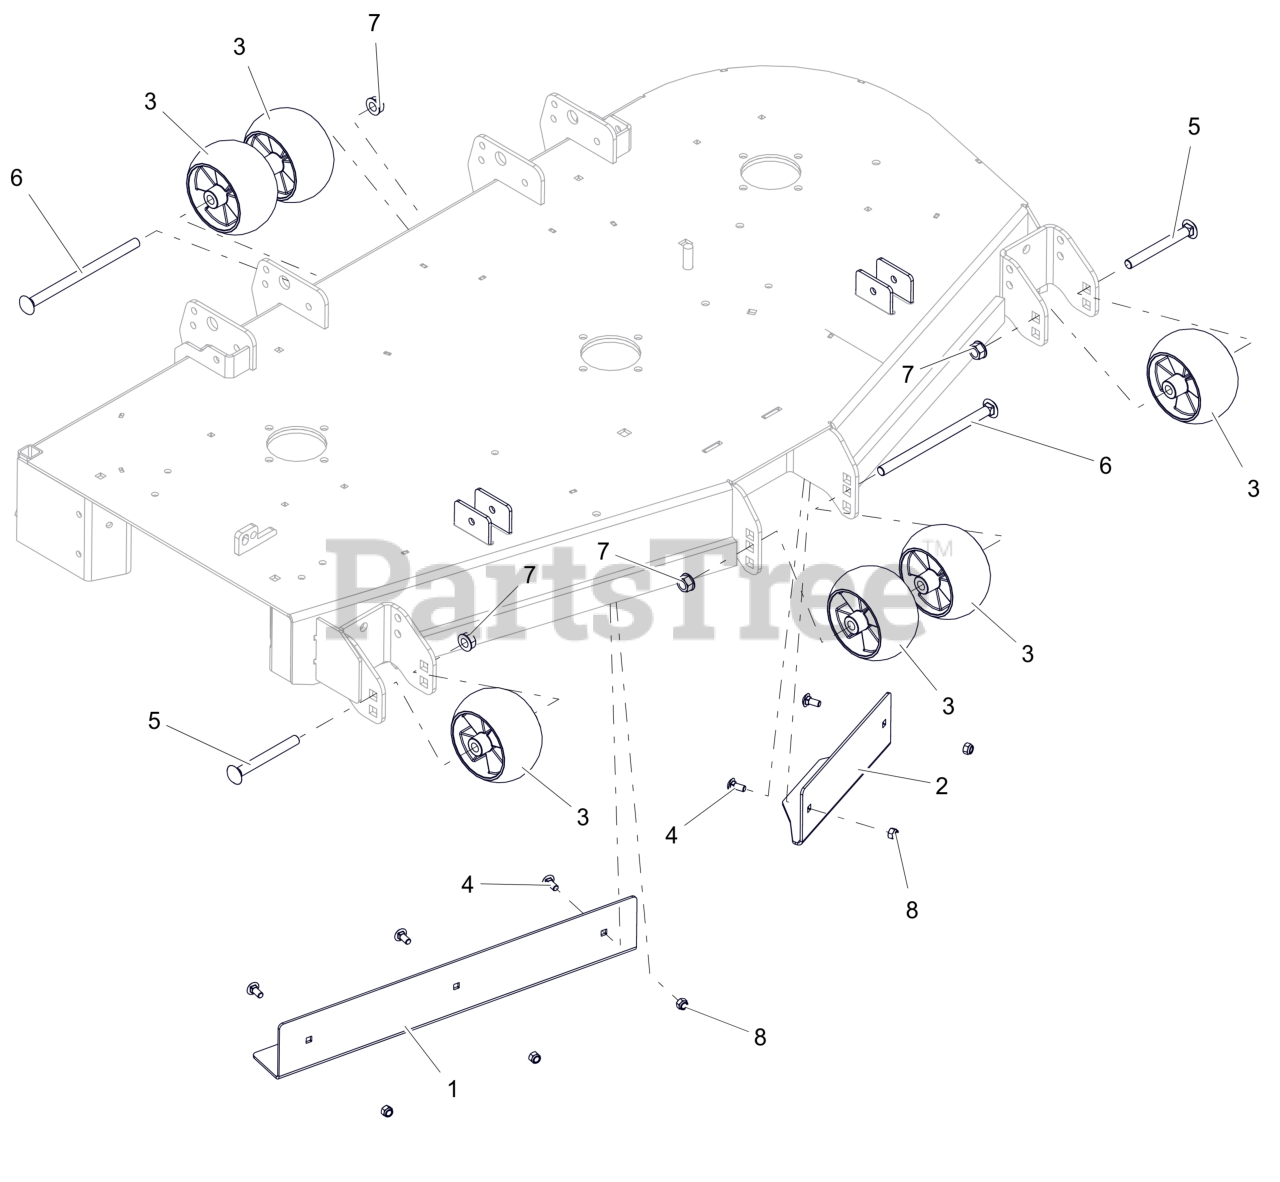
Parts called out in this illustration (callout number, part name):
1	BAFFLE, 52" RH VACUUM (RED)
2	BAFFLE, 52" LH VACUUM (RED)
3	WHEEL, ANTI SCALP - 5X3 CTR W/RIBS
4	BLT,RHSN .31-18X.75 G5 ZCC
5	BLT,RHNS .50-13X4.50 G5 ZCC NS
6	BLT,RHSN .50-13X8.00 G5 ZCC NS
7	NUT-LK-CTR-FLG .500-13 GG ZCC
8	NUT,NYL .31-18 G5 ZCC
